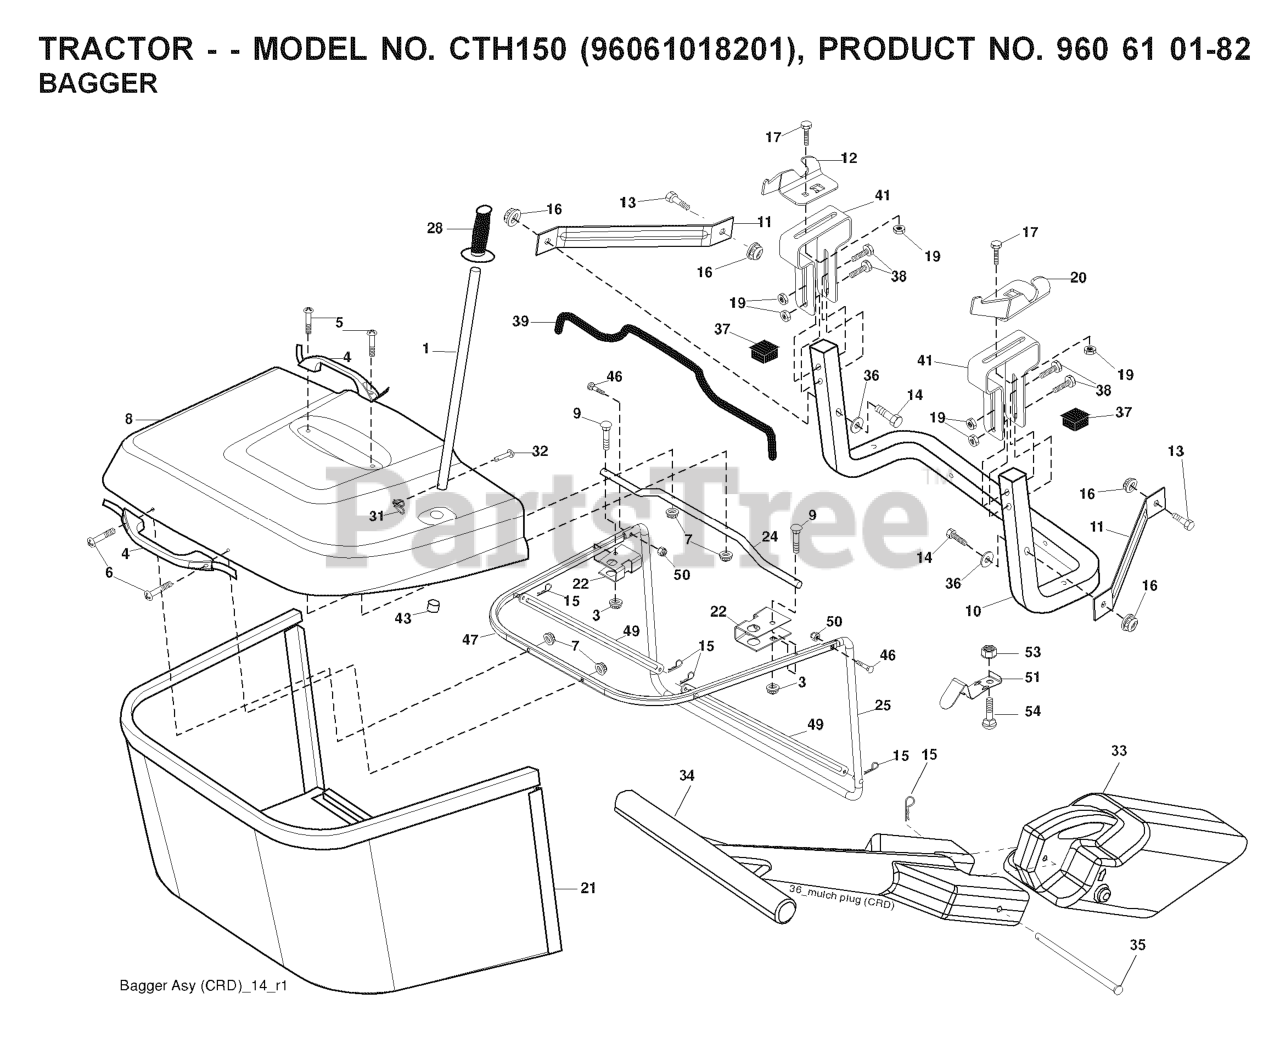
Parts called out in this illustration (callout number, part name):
1	TUBE HANDLE
3	NUT T
4	HANDLE.BAGGER.W/LVRS.BLK.CRD
5	SCREW.PAN.HEAD
6	REPL BY 532 75 00-29
8	COVER.PNT.BGR.CRD.WSLOTS.MS668
9	Bolt Carriage 1/4-20 x 2.25d x Gr.5
10	TUBE
11	BRACKET.SUPPORT.UPPER.BAG.CRD
12	BRKT PIVOT
14	BOLT-HEX EAK
15	RETAINER-SPRNG RB
16	NUT LOCK FLG 3/8-16 UNC
17	RP BOLT 5/16-18 X3/4 ZN/YEL GR
19	NUT LOCK HEX FLANGE 5/16-18
20	BRKT.PIVOT.RH.CRD
21	BAGGER.ASM.CRD.2007
22	BRKT.SIDE.BAG.CRD
24	TUBE.PIVOT.BAG.CRD.BLACK
25	PIPE
28	GRIP.HANDLE.BLACK
31	RETAINER CLIP
32	RIVET,DRILLED
33	MULCH PLUG, CTH150
34	HANDLE.MULCHER.92.CRD (2 2)
36	WASHER
37	Plug Support Bagger CRD
38	BOLT.5/16-18X2.5
39	SEAL.TRIM.37'
41	BRKT.VERT.ADJ.BAGGER.CRD
43	PLUG, TUBING END
46	BOLT.CARRIAGE.5/16-18
47	PIPE
49	ROD
50	NUT.71038.31-18.HEX.NYLOCK
51	LATCH
53	NUT
54	BOLT
